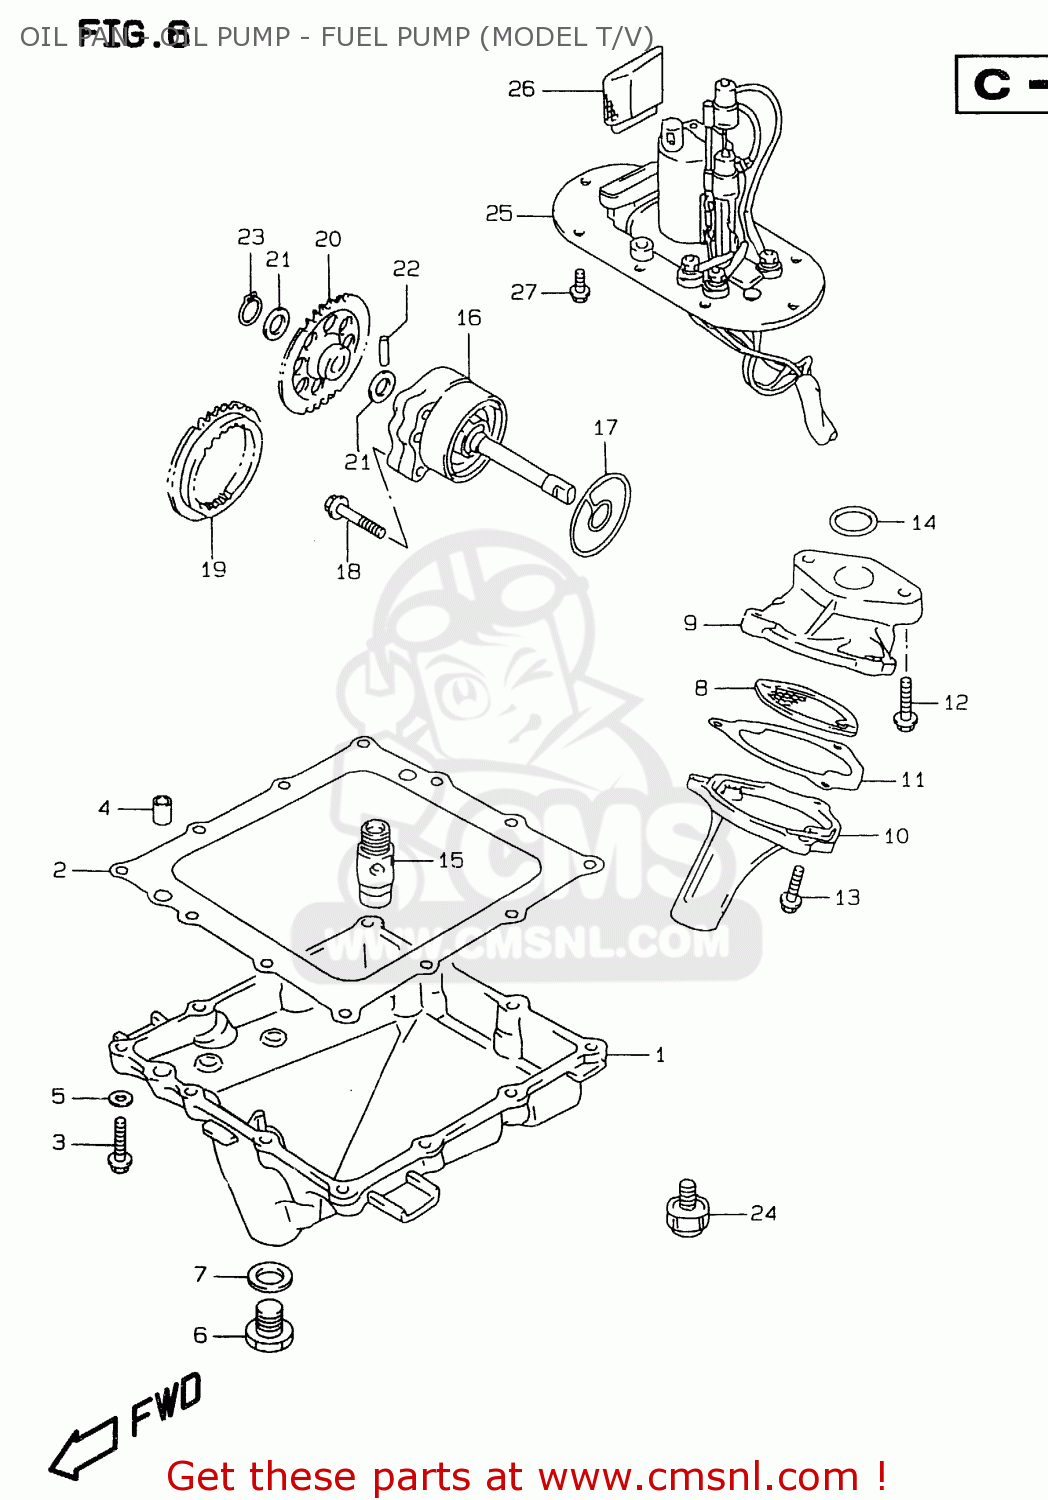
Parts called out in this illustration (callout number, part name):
1	PAN,OIL
2	GASKET,OIL PAN (NAS)
3	BOLT
4	PIN
5	GASKET(5.8X11X1.2) (NAS)
6	PLUG
7	GASKET(13.8X18.8X4.8) (NAS)
8	STRAINER,ENGINE OIL
9	PROTECTOR,OIL STRAINER
10	COVER,OIL STRAINER
11	GASKET,OIL STRAINER
12	BOLT
13	BOLT
14	O RING(D:2.62,ID:20.3)
15	VALVE ASSY,OIL RELIEF
16	PUMP ASSY,ENGINE OIL
17	O RING,OIL PUMP
18	BOLT
19	GEAR,OIL PUMP DRIVE (NT
20	GEAR,OIL PUMP DRIVEN(NT:37)
21	SHIM
22	PIN(5X18)
23	CIRCLIP,12 MM
24	SWITCH ASSEMBLY,OIL PRESSURE
25	PUMP ASSEMBLY,FUEL
26	STRAINER,FUEL PUMP
27	BOLT
